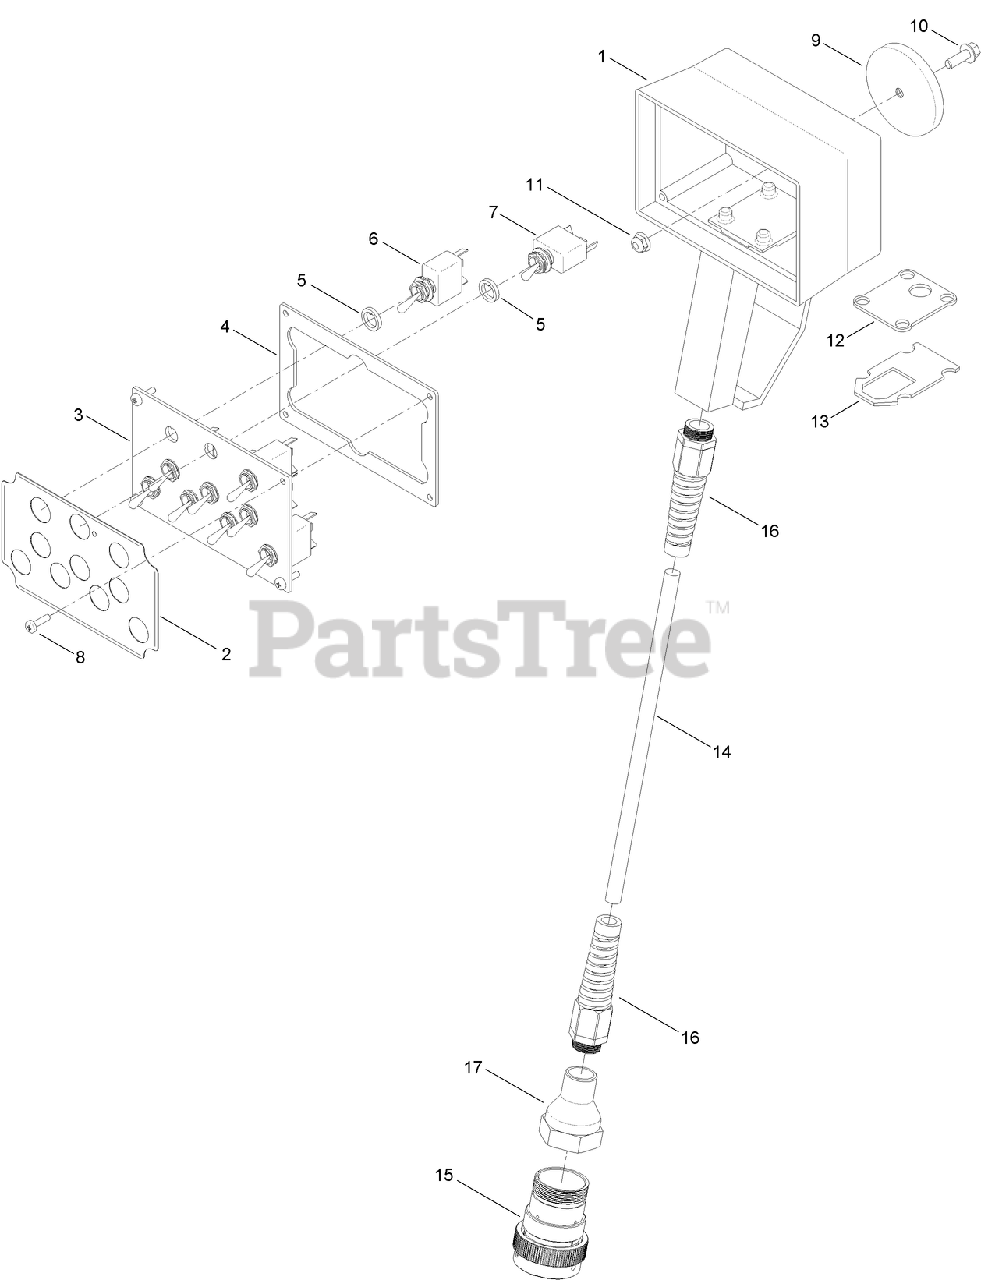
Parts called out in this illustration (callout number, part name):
1	ENCLOSURE-HANDHELD
2	DECAL-LIFE JACKET
3	PLATE-LIFE JACKET
4	GASKET-LIFE JACKET
5	SEAL-SWITCH
6	SWITCH
7	SWITCH
8	SCREW-PPH
9	MAGNET-CERAMIC, ENCASED
10	SCREW-HHF
11	NUT-HF
12	GASKET-HANDLE, INNER
13	GASKET-HANDLE, OUTTER
14	CABLE-LIFE JACKET
15	DEUTSCH 23F
16	GRIP-CORD
17	COUPLER
